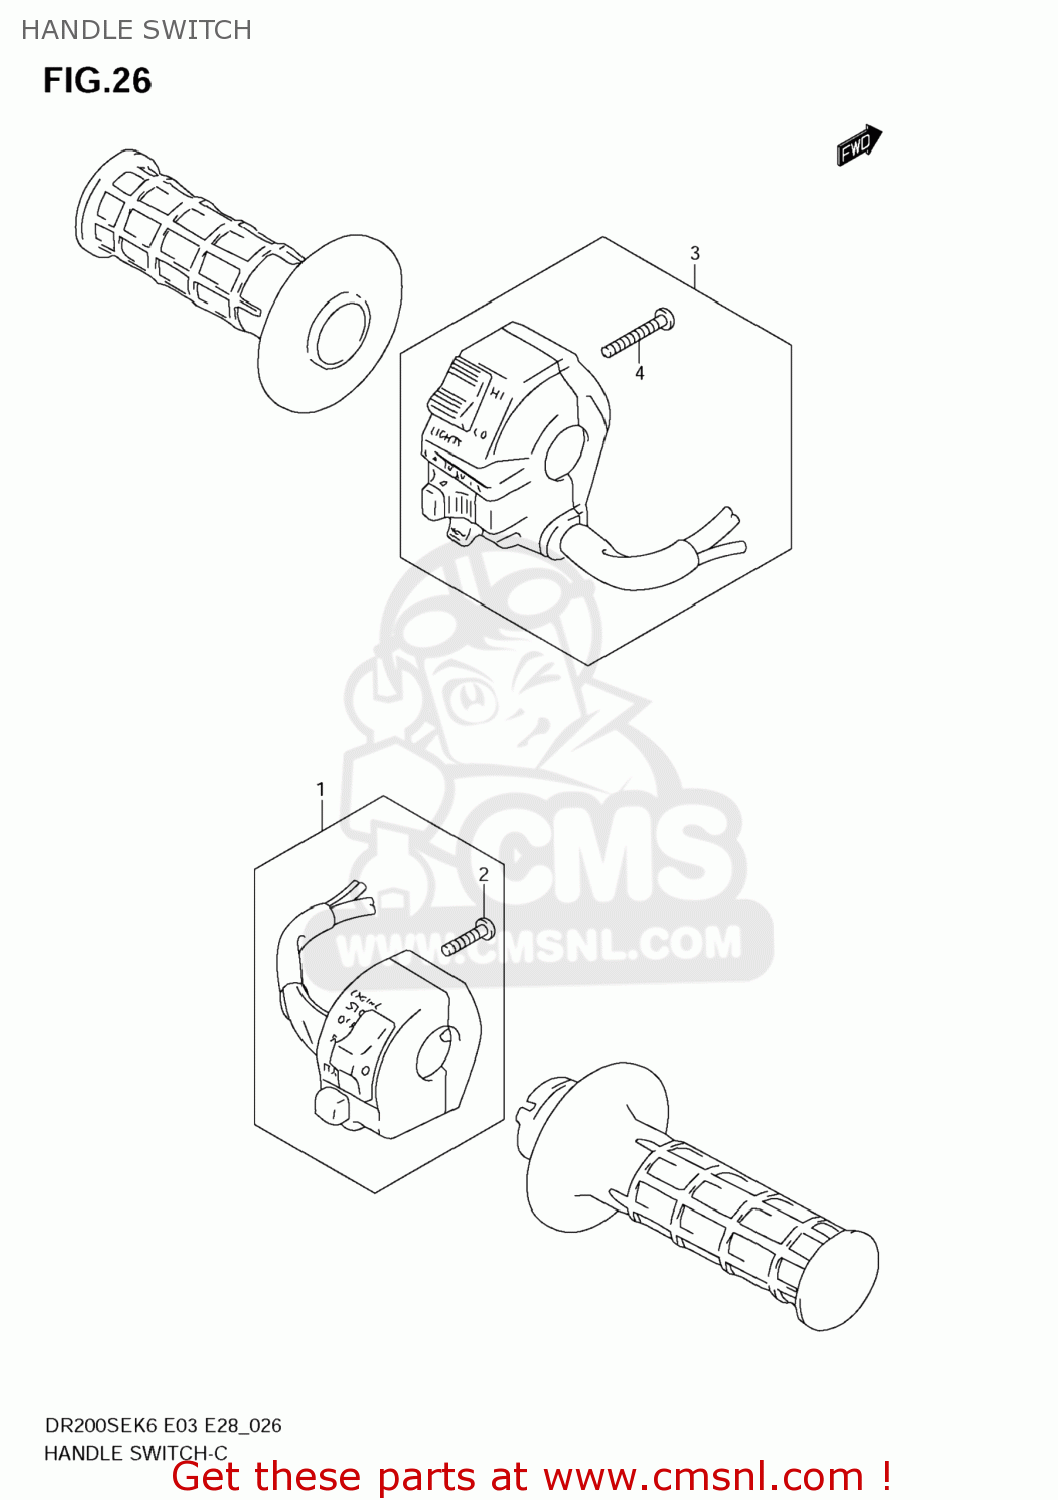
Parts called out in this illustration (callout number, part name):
1	SWITCH ASSY,HANDLE,R
2	SCREW
3	SWITCH ASSEMBLY,HANDLE,LEFT
4	SCREW
